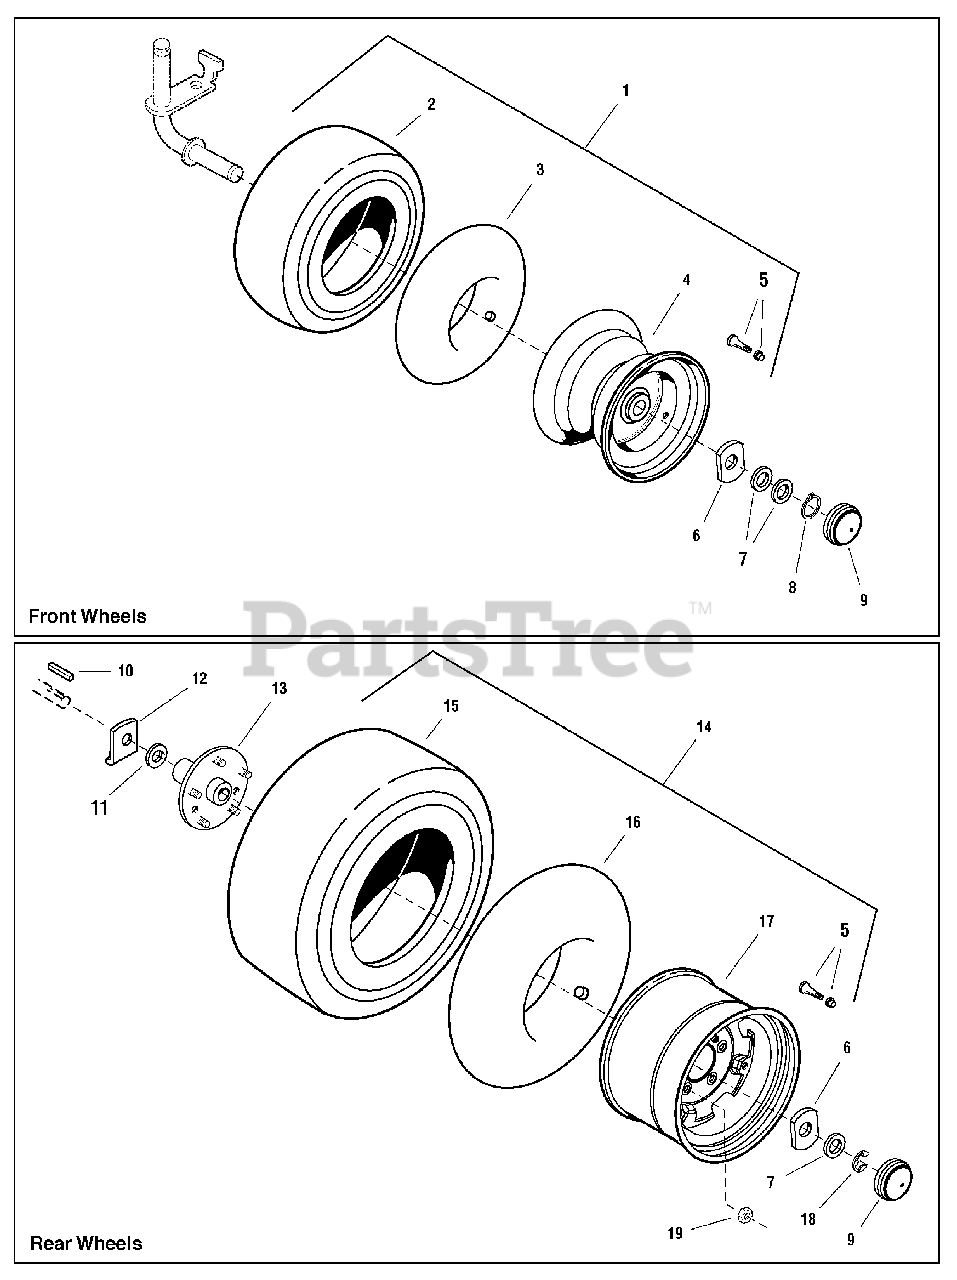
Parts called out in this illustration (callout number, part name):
1	WHEEL & TIRE ASSEMBLY, Front, (Includes Ref. Nos. 2, 3, 4 & 5)
2	TIRE, 24 x 12 - 12, Front
3	TUBE, Tire 23 x 10-1/2 - 12, Front
4	WHEEL, 12 x 8-1/2, Front
5	VALVE STEM & CAP ASSEMBLY
6	WASHER, Special, 1 x 2-1/2
7	WASHER
8	RING, Retainer
9	CAP, Hub Grey, 2-23/64
10	KEY, HI PRO, 1/4 x 2
12	WASHER, Axle Seal
13	PLATE & HUB ASSEMBLY, Rear Wheel w/Studs
14	WHEEL & TIRE ASSEMBLY, Rear 23" (Includes Ref. Nos. 5, 15, 16 & 17)
15	TIRE, 23 x 10-1/2 - 12 Super Turf, Rear
16	TUBE, Tire 23 x 10-1/2 - 12, Rear
17	WHEEL, 7 x 12, Rear
18	RING, Shaft
19	NUT, Hex 7/16-20, For Wheel Bolt
